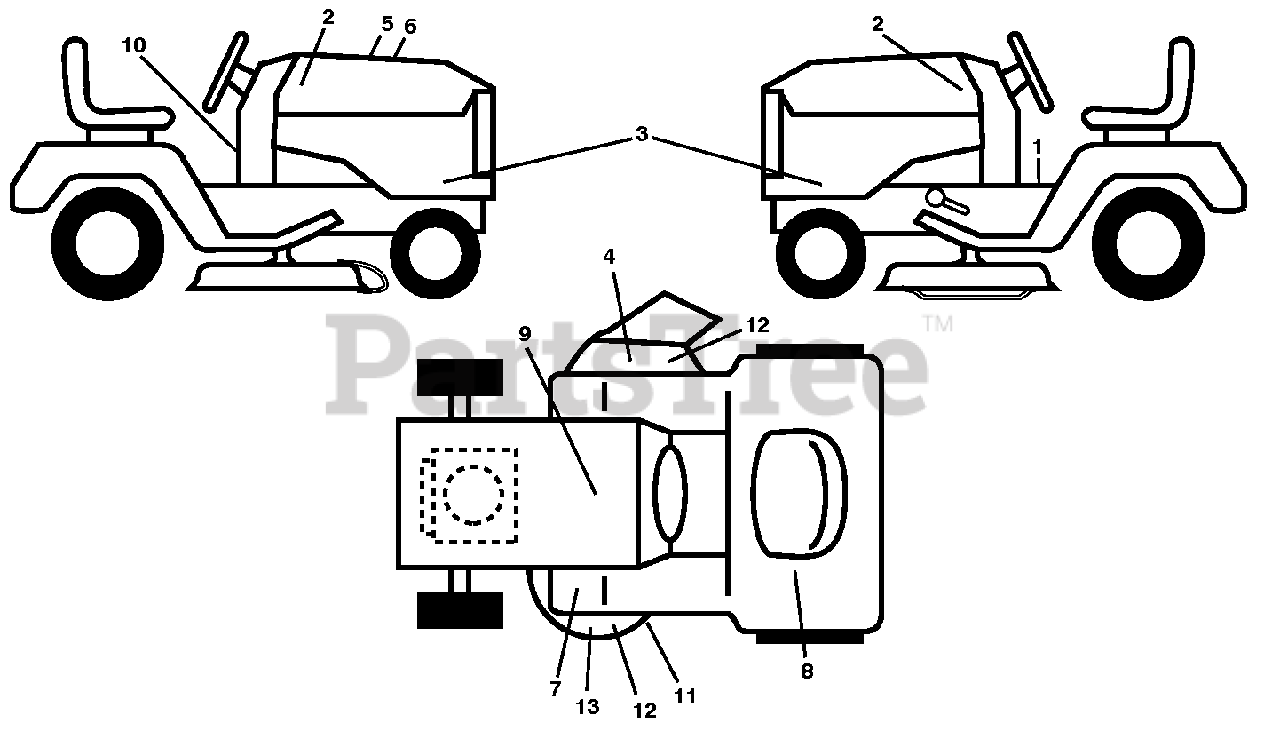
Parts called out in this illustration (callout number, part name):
1	DECAL.FENDER.WARNING.ENGLISH
2	DECAL.BADGE.170MM.TEXTLOGO.
3	DECAL.SDPL.HUSQGT2.YT.48XLS
4	DECAL.DECK.6MIL./DEF.SHLD.WARN
5	DECAL.WARNING.CUST.RESP.E85.
7	DECAL.PEDAL.HUSQ.CROWN
8	DECAL.WARN.FUEL.RESERVE
9	DECAL BTRY SYMBOLS
10	DECAL, WARNING SPARK ARRESTOR
11	DECAL.MOWER.SCH.48/54.PREM
12	DECAL.DECK.6MIL.EURO.NOSTEP
13	DECAL.HV.REINFORCED.DECKS.2012
